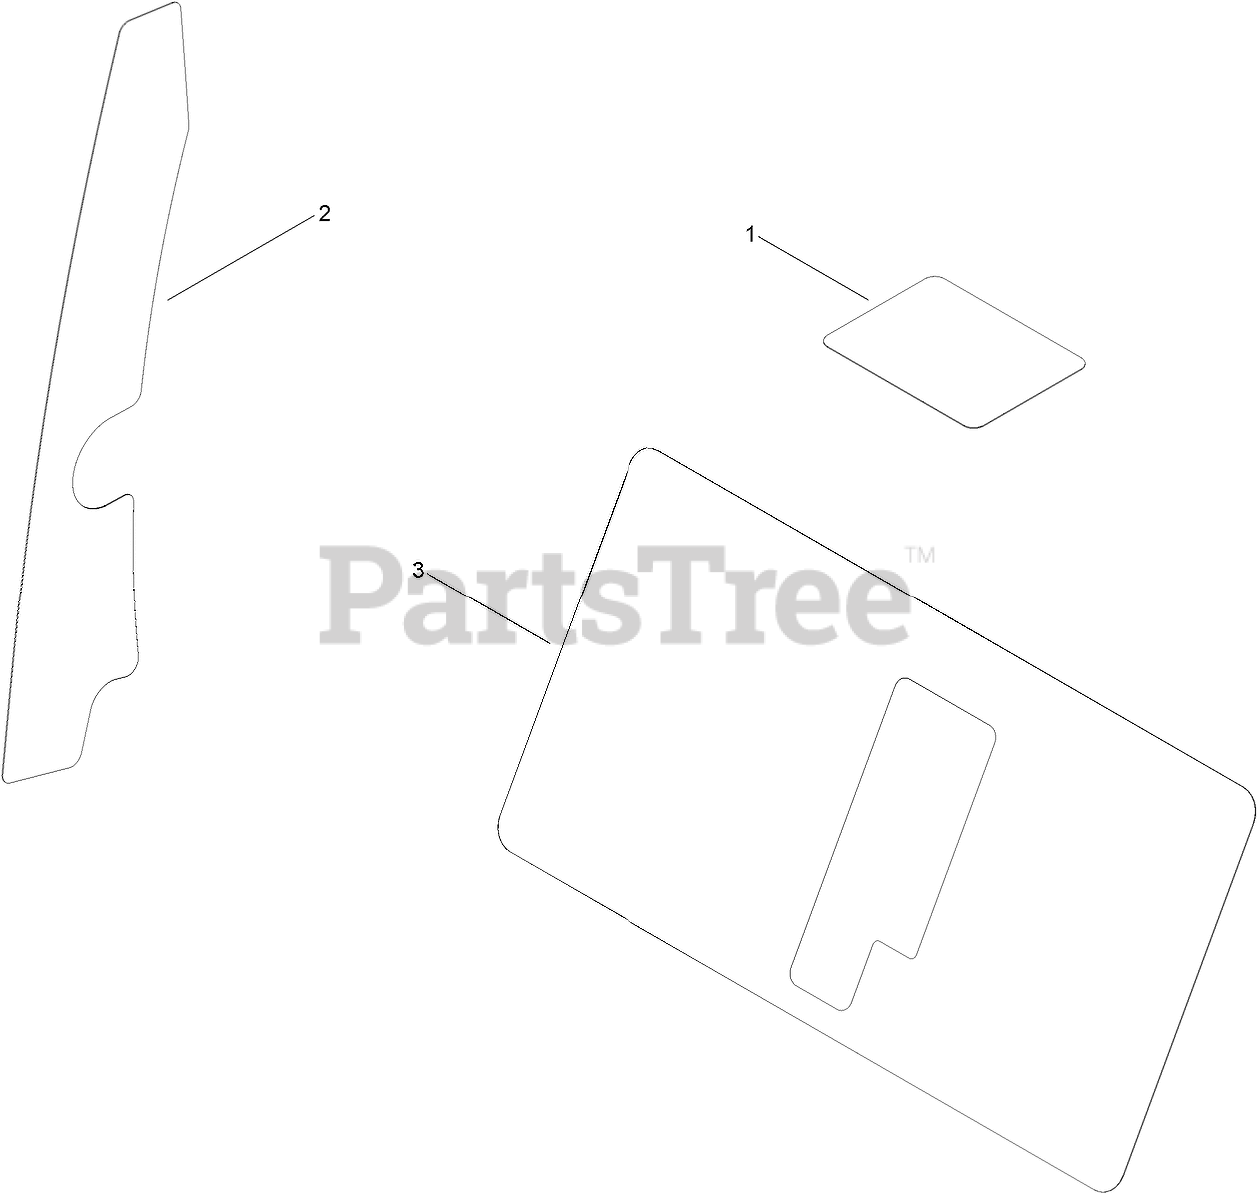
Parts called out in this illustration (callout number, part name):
1	DECAL-MAINTENANCE
2	DECAL-HOC
3	DECAL-CONTROL, SPEED
